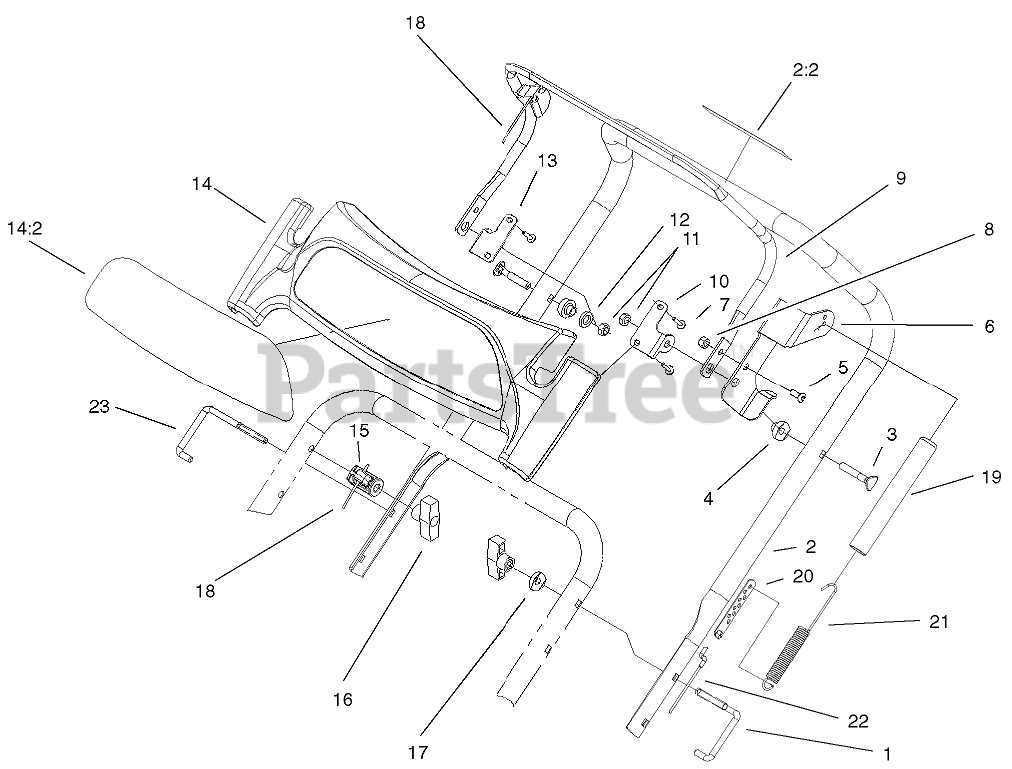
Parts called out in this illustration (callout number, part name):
1	LOCK-HANDLE
2	Handle-Upper W/Decal (only on: 38600, 38602)
2	Handle-Upper W/Decal (only on: 38601, 38603)
2:2	Decal-Rotor Drive (only on: 38600, 38602)
2:2	Decal-Rotor Drive, (Ce)(only on: 38601, 38603)
3	SCREW-HANDLE
4	SPACER-BAR, CONTROL
5	SCREW-HSBH
6	ARM-CLUTCH, HANDLE
7	SCREW-HWH
8	NUT-LOCK, NI
9	BAR-CONTROL
10	BRACKET-PANEL, LH
11	NUT-LOCK, NI
12	WASHER
13	BRACKET-PANEL, RH
14	PANEL-DISPLAY HANDLE W/DECAL
14:2	DECAL-DISPLAY HANDLE
15	GUIDE-Cable, PIVOT
16	KNOB-HANDLE
17	WASHER-CURVED
18	CABLE-PIVOT
19	COVER-SPRING
20	ADJUSTER-CABLE, CLUTCH
21	SPRING-CABLE
22	CABLE-CLUTCH
23	LOCK-HANDLE, RH
